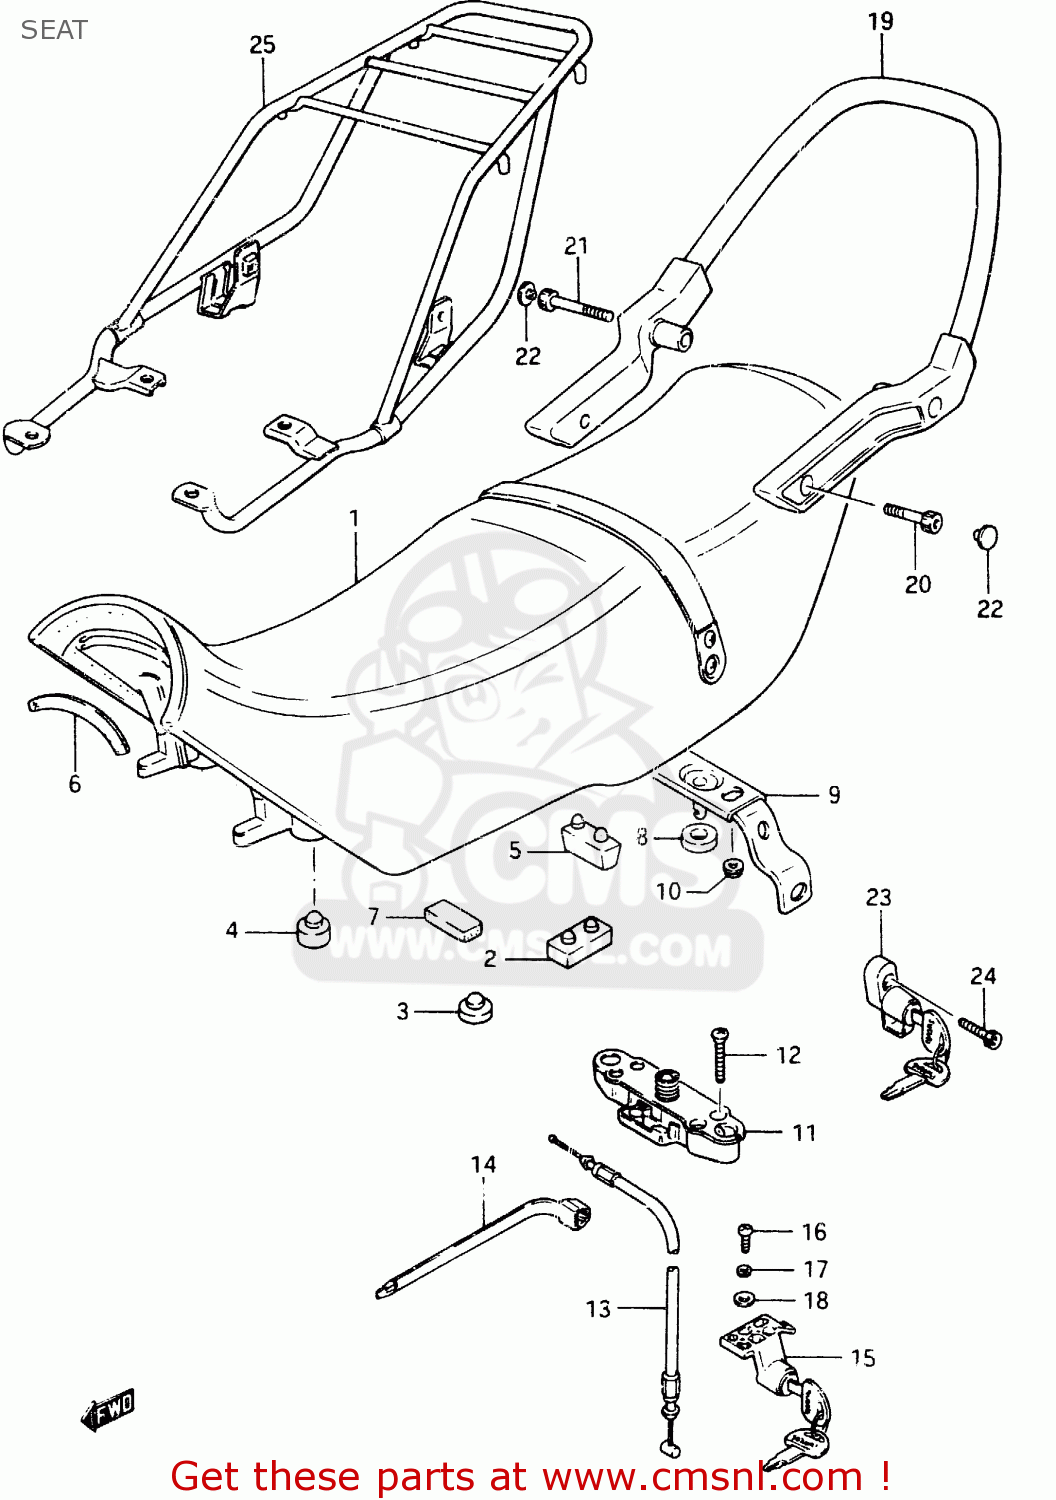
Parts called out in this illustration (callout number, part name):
1	SEAT ASSY (BLACK)
2	CUSHION,SEAT(40X20X15)
3	CUSHION
4	CUSHION
5	CUSHION,SUPPORT(50X25X32)
6	WEATHERSTRIP,SEAT
7	CUSHION,TOOL(40X30X15)
8	CUSHION
9	PLATE,SEAT LOCK STRIKE
10	NUT
11	LOCK ASSY,SEAT STRIKER
12	SCREW,6X30
13	CABLE,SEAT LOCK
14	CLAMP(L:165)
15	LOCK ASSEMBLY,SEAT
16	SCREW
17	WASHER,LOCK
18	WASHER,5MM
19	HANDLE, PILLION RIDER
20	BOLT, REAR (8X30)
21	BOLT, REAR
22	CAP(OD:19.5)
23	LOCK SET
24	BOLT
25	CARRIER, SPORTS
